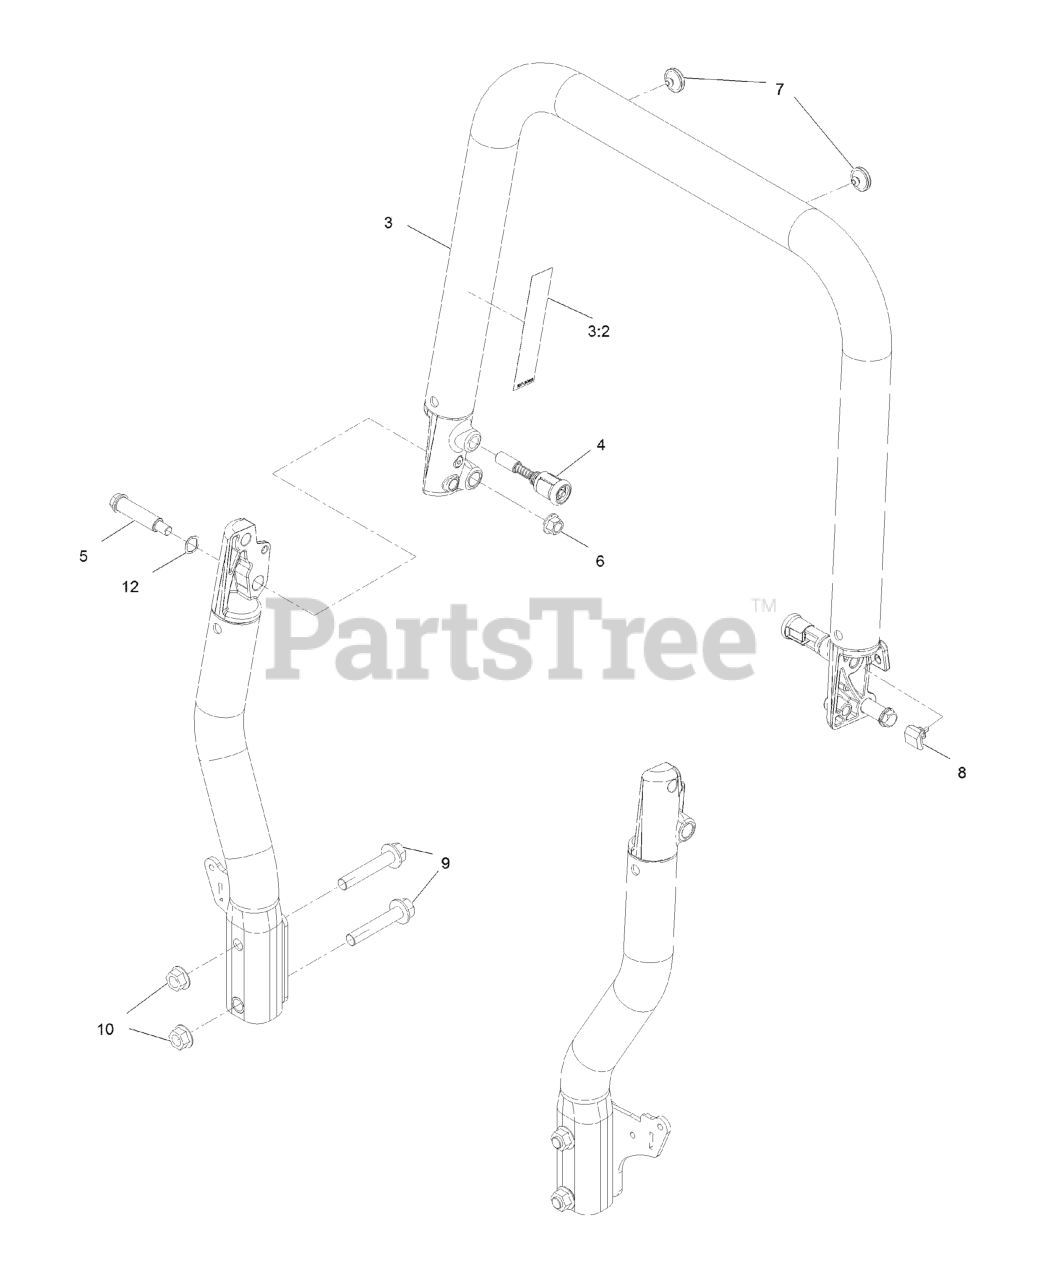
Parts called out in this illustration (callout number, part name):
3	TOP TUBE ASM
3:2	DECAL-WARNING
4	PIN-SPRING
5	BOLT-SHOULDER
6	Nut-Lock 1/2-13
7	BUMPER-ROPS
8	BUMPER-ROPS
9	SCREW-HHF
10	NUT-FLANGE
12	WASHER-WAVE
